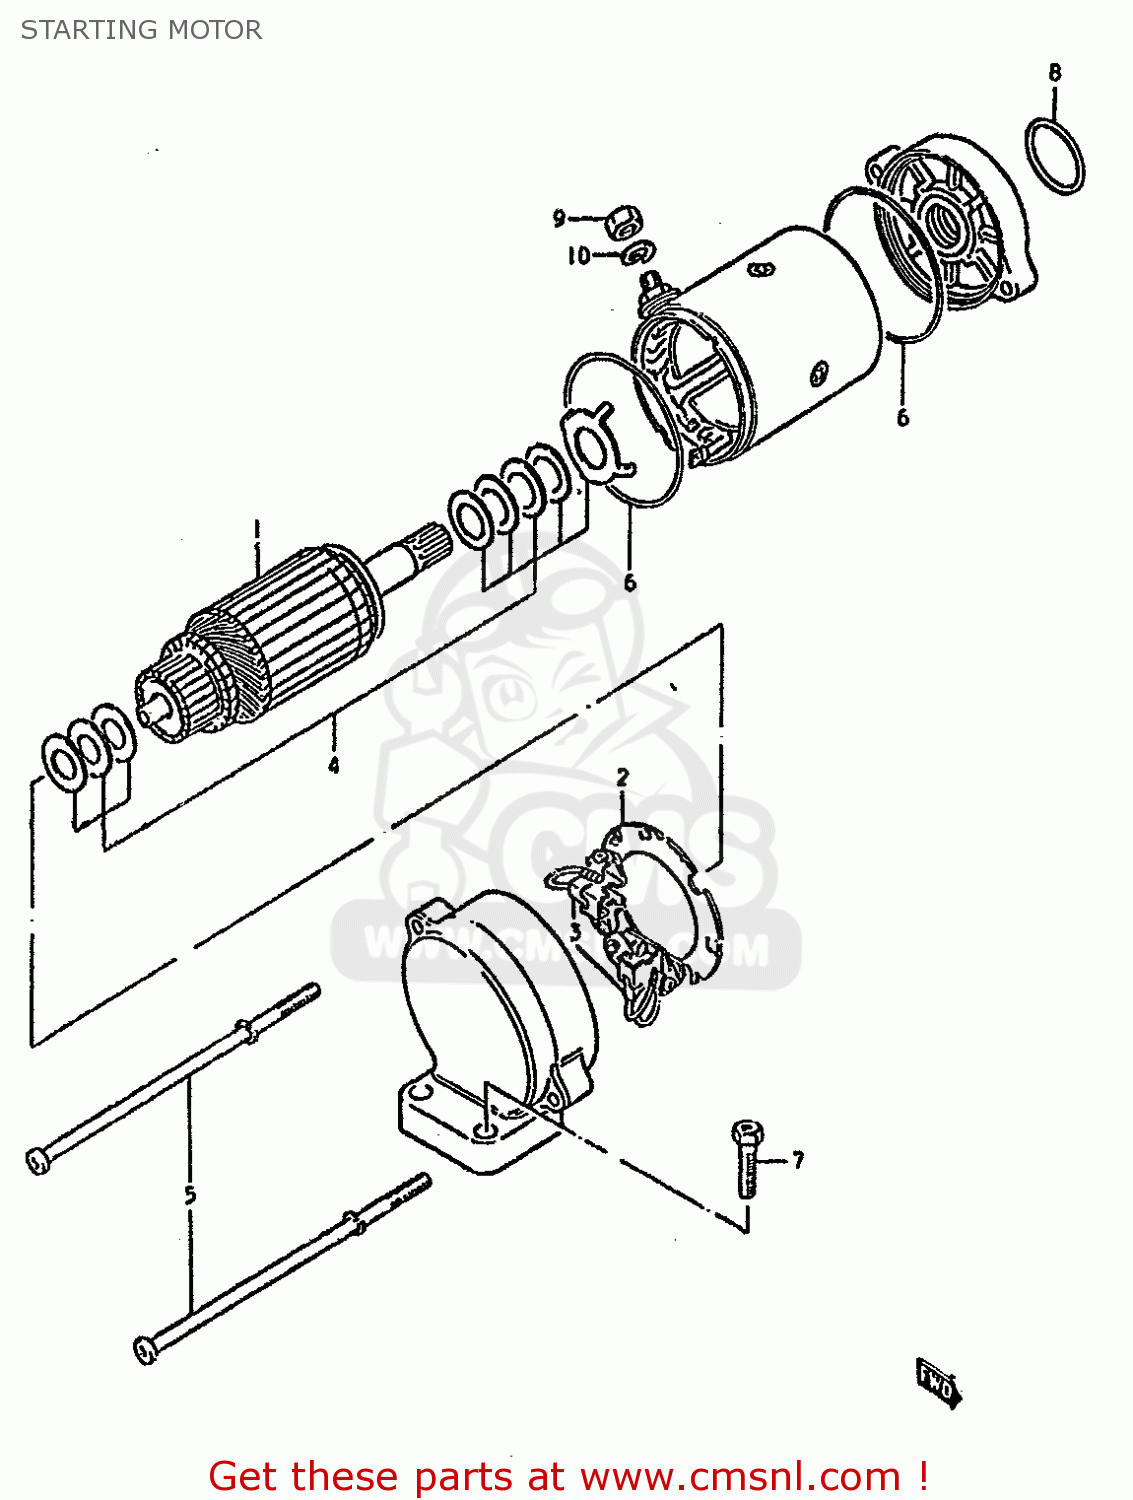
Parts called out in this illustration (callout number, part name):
1	ARMATURE
2	HOLDER ASSY
3	BRUSH SET
4	SHIM SET
5	BOLT,STARTING MOTOR HOUSING
6	O RING
7	SCREW (6X25)
8	O RING(D:2,ID:24.5)
9	NUT 6MM
10	LOCK WASHER
